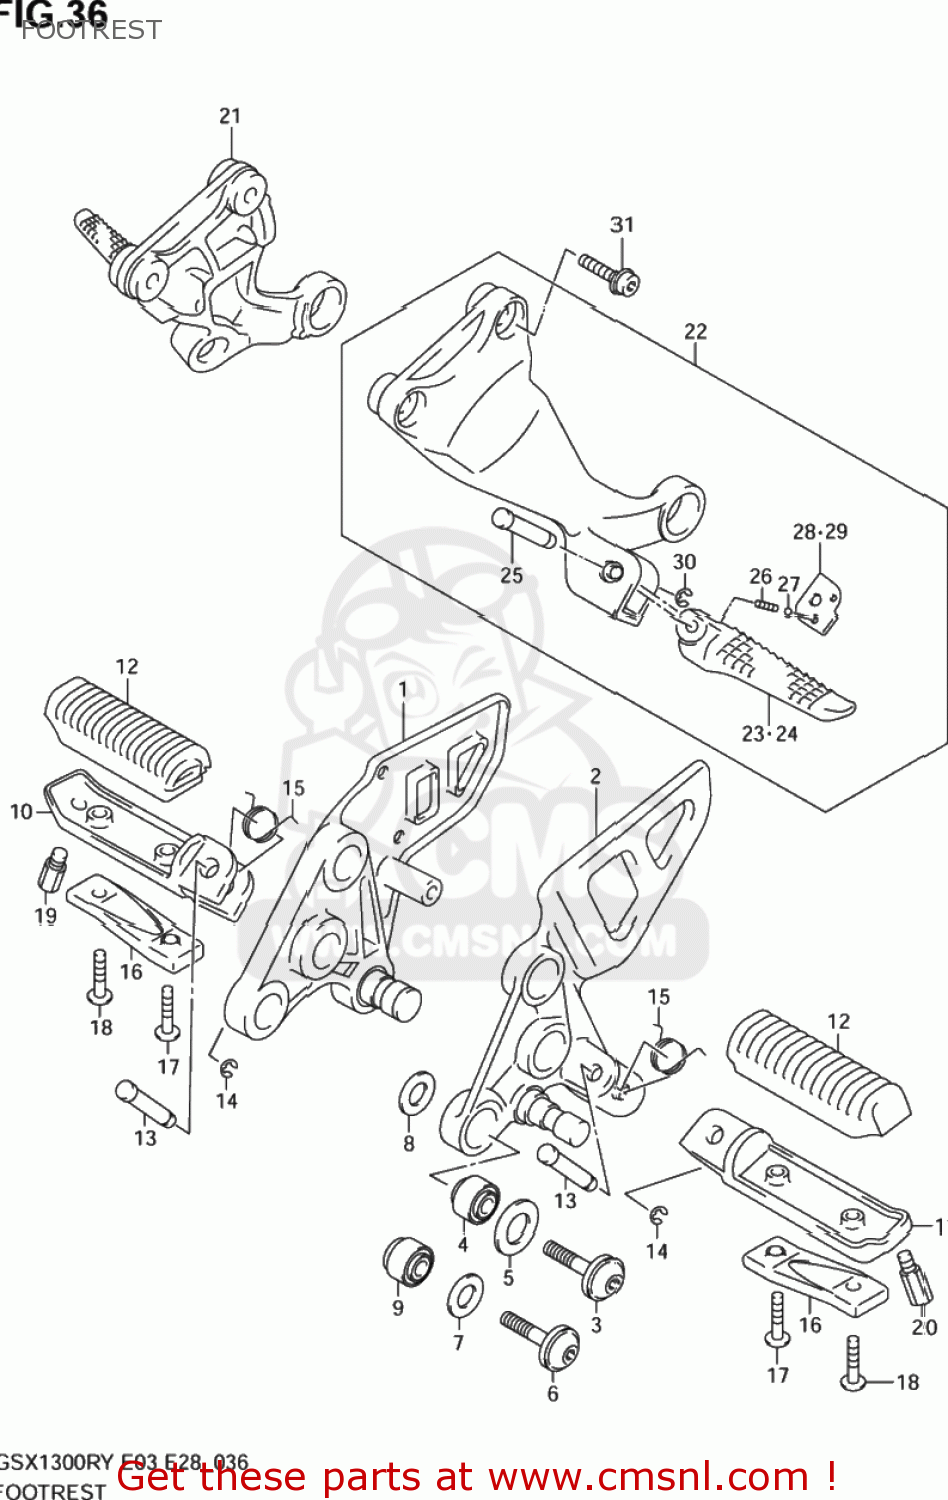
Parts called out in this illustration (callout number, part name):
1	BRACKET,FR FOOTREST,R
2	BRACKET,FR FOOTREST,L
3	BOLT
4	BUSH(12X20X16)
5	WASHER(12.6X24X2.2)
6	BOLT(8X30)
7	WASHER(13.7X24X2)
8	WASHER(17.2X24X2.2)
9	BUSH(8.4X20X16)
10	BAR,FR FOOTREST,R
11	BAR,FR FOOTREST,L
12	RUBBER,FOOTREST BAR
13	PIN
14	E.RING
15	SPRING
16	BALANCER,FR FOOTREST LWR
17	SCREW
18	SCREW
19	BOLT,BANK SENSOR
20	BOLT,BANK SENSOR
21	FOOTREST ASSY,PILLION,R
22	FOOTREST ASSY,PILLION,L
23	BAR,PILLION FOOTREST,R
24	BAR,PILLION FOOTREST,L
25	PIN
26	SPRING
27	BALL
28	PLATE,PILLION FOOT,R
29	PLATE,PILLION FOOT,L
30	E-RING
31	BOLT(8X30)
